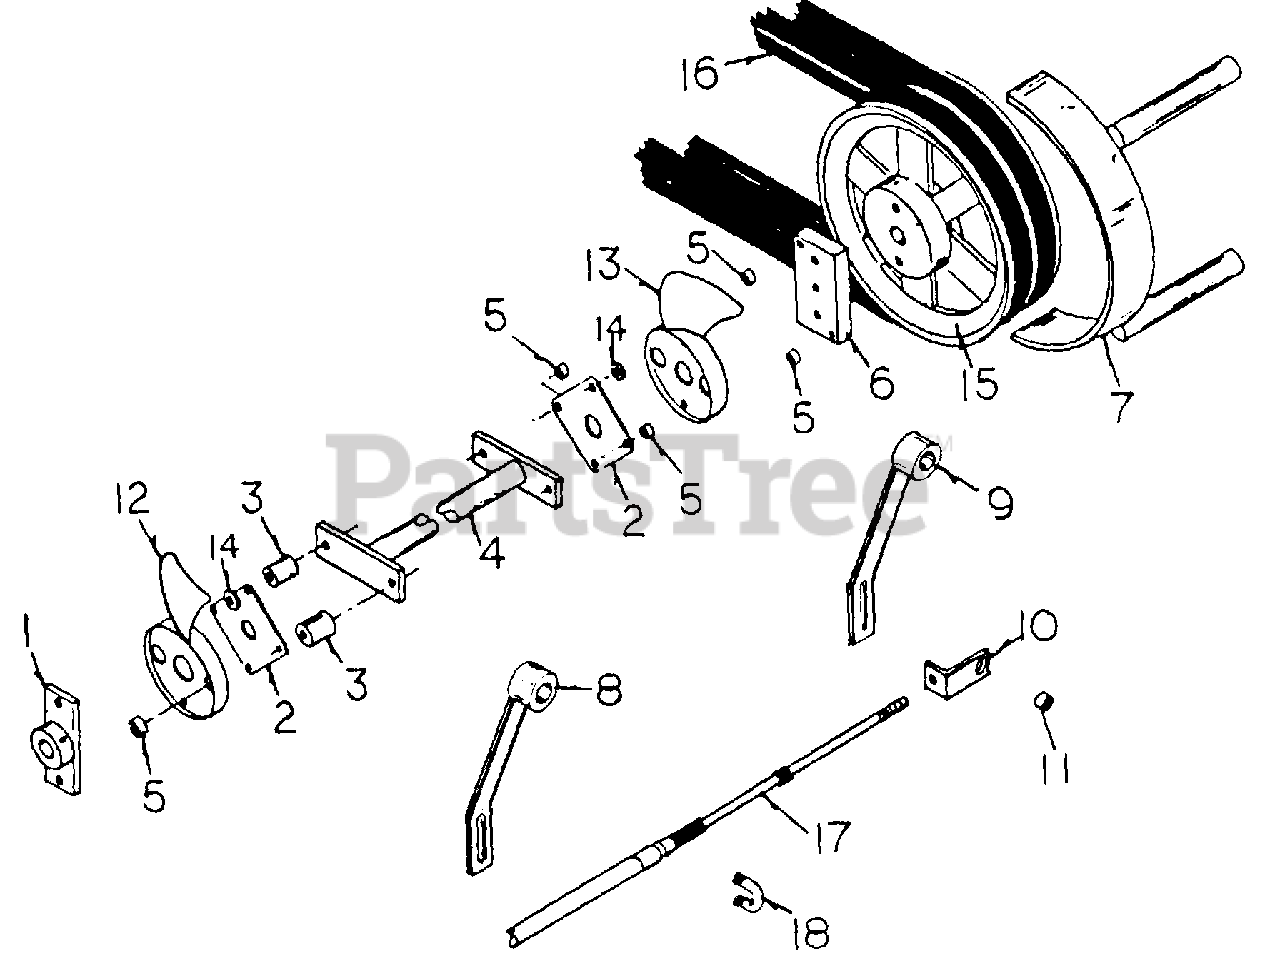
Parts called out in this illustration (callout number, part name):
1	HUB - w/drive plate
2	DRIVE PLATE
6	CROSS BAR BLOCK
7	TRANSMISSION BELT RETAINER
8	TRANSMISSION ARM - L.H.
9	TRANSMISSION ARM - R.H.
10	STEERING CABLE ENDS
11	STEERING CABLE ENDS BUSHING
12	CCW FAN - L.H.
14	WASHER - 5/16"
17	STEERING CABLE
